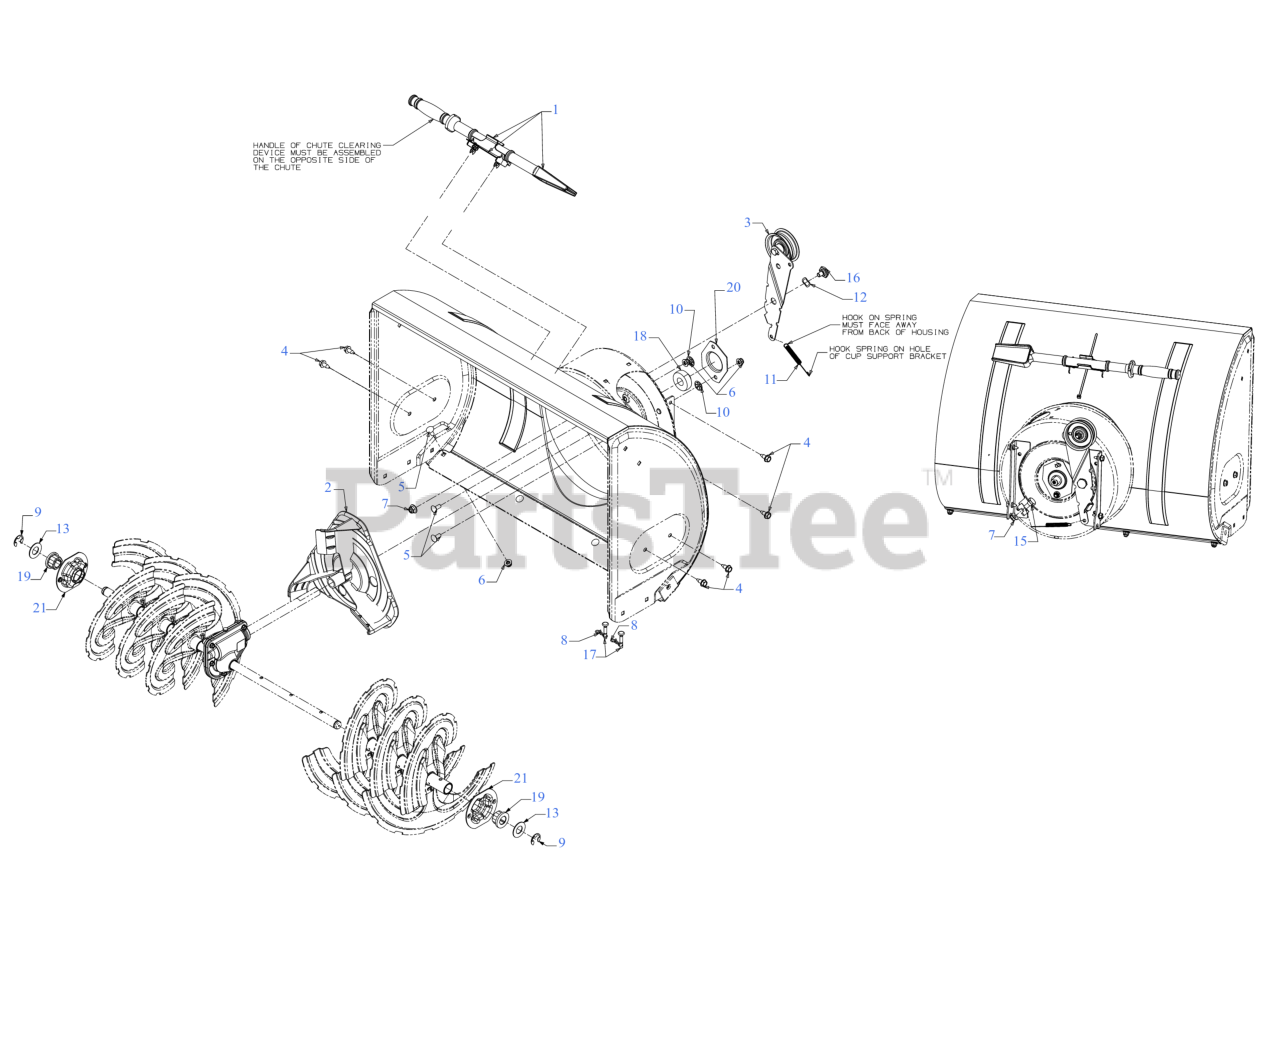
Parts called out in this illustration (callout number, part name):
1	CLEANOUT TOOL
1	CLEANOUT TOOL MOUNTING CLIP
4	SCREW 5/16-18 x .750
5	CARRIAGE BOLT 5/16-18 x .75
6	FLANGE LOCK NUT 5/16-18
8	BOW TIE COTTER PIN 1/4-5/16
9	E-RING
10	PUSH NUT
11	EXTENSION SPRING .38 OD x 4.59
12	WAVE WASHER .660 ID X.88 OD x .010
13	FLAT WASHER .760ID X1.49OD x .06
15	SHOULDER SCREW .498 DIA x .340
16	SHOULDER SCREW .625 DIA x .163
17	SHEAR PIN .25 x 1.50 GR2
17	Cub Cadet SHEAR PINS (2X SNOW)
17	SHEAR PINS QTY 4
18	BEARING W/OUT COLLAR
19	FLANGE BEARING
20	BEARING HOUSING 1.85 ID
